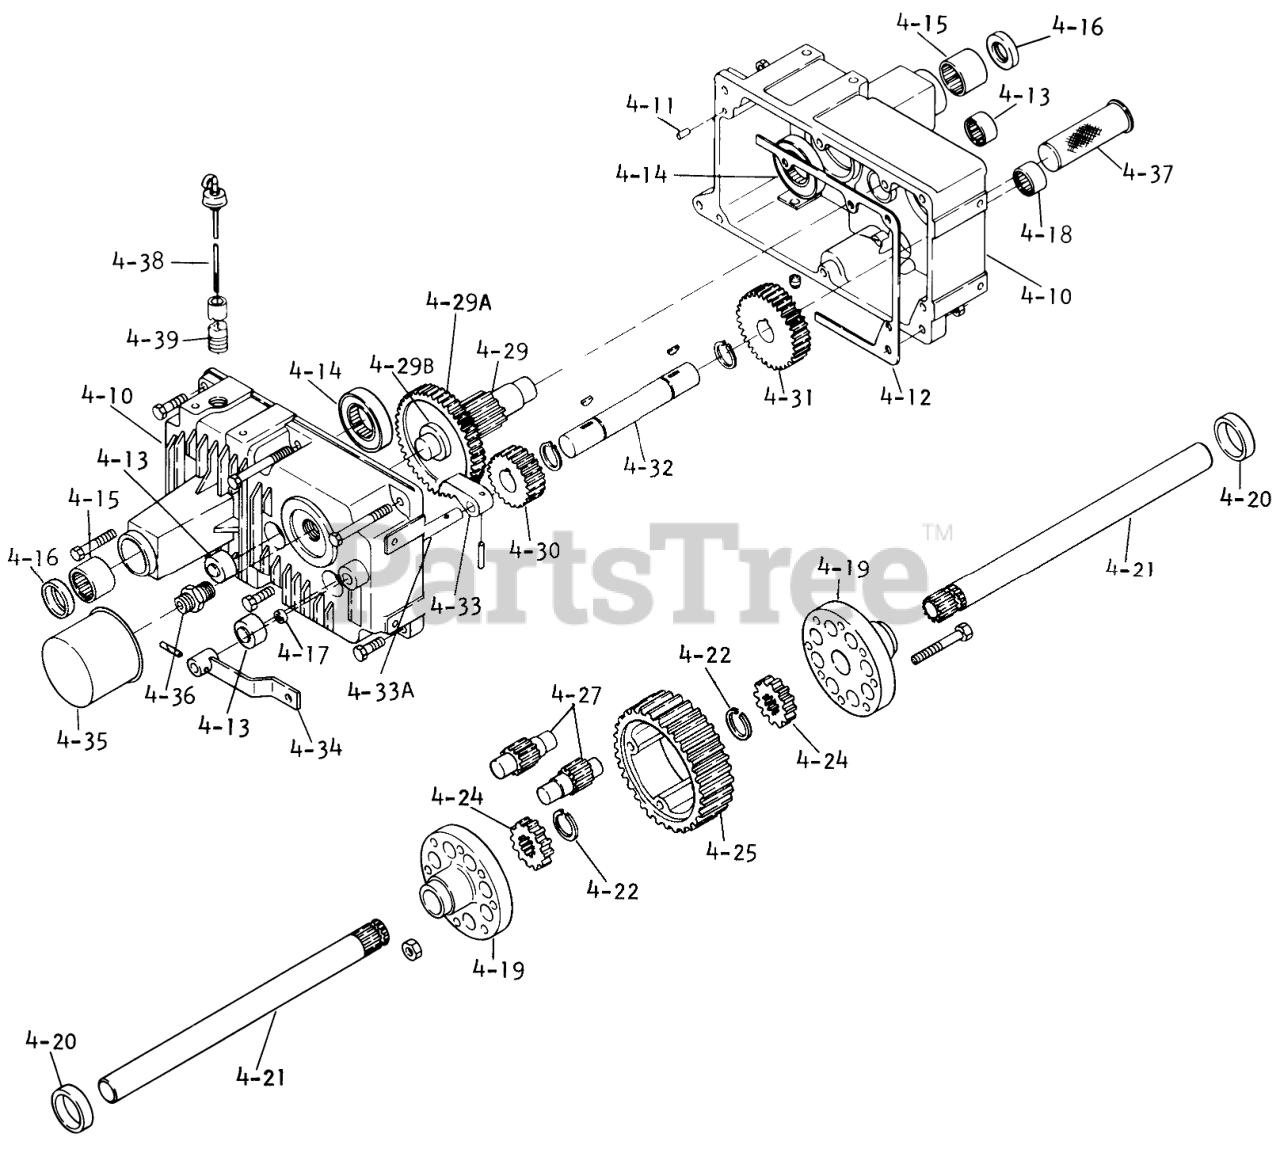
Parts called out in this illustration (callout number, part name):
4-10	RH TRANSMISSION CASE
4-11	PIN-DOWEL
4-12	GASKET
4-13	BEARING-NEEDLE
4-14	NEEDLE BEARING
4-15	Bearing-Axle
4-16	SEAL-OIL
4-17	SEAL BRAKE SHAFT
4-18	Needle Bearing
4-19	End Cap
4-20	RACE BEARING
4-21	REAR AXLE
4-22	SNAP RING
4-24	GEAR-AXLE DIFFERENTIAL
4-25	Gear-Bull
4-27	GEAR-PINION, 11T
4-29	PINION SHAFT
4-29A	GEAR 46T
4-29B	WASHER-THRUST
4-30	20T GEAR
4-31	Gear 44T
4-32	SHAFT GEAR
4-33	Parking Pawl
4-33A	Parking Shaft
4-34	Brake Lever Assy.
4-35	Filter
4-36	FITTING
4-37	Strainer
4-38	Dipstick Assy.
4-39	Nipple-Pipe-1/2 X 11 1/4
